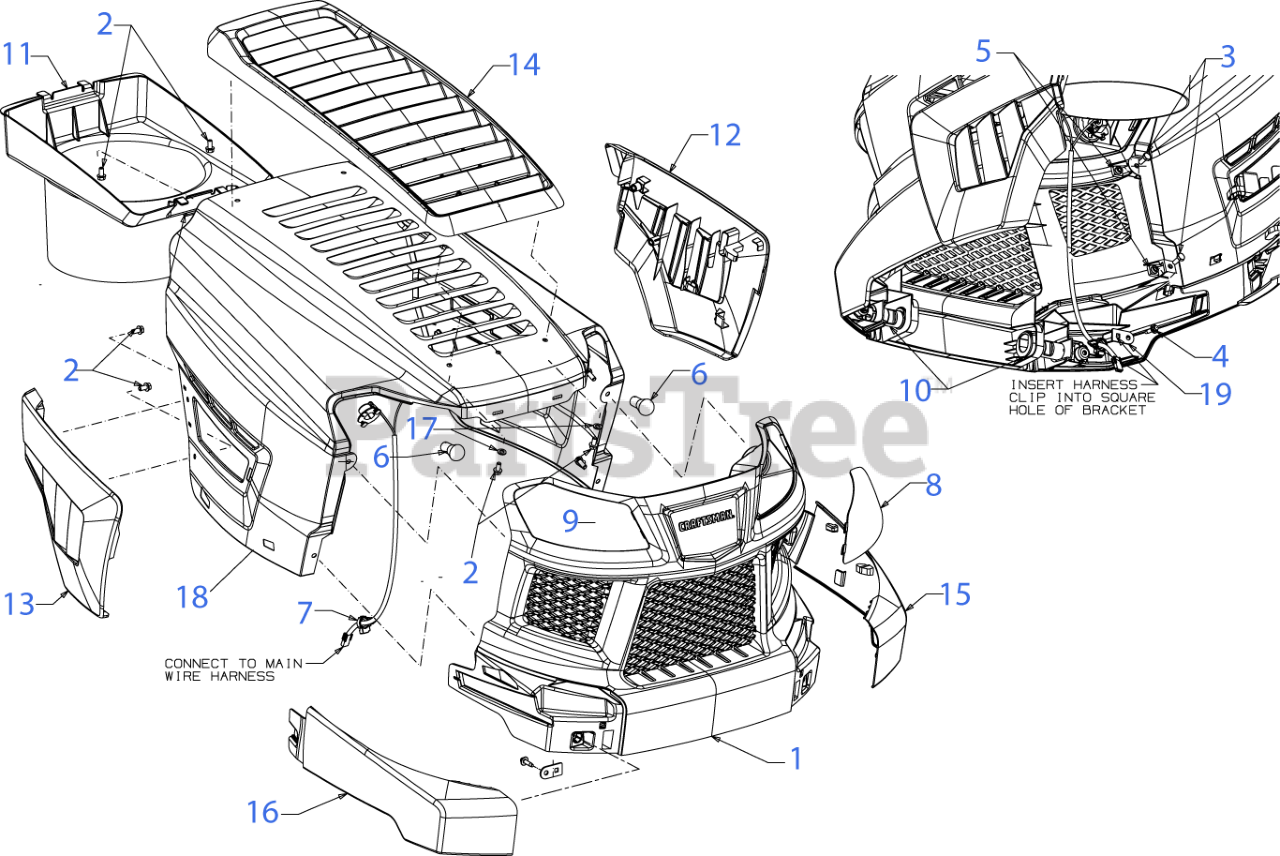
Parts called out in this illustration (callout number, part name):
1	GRILLE
2	HEX SCREW 1/4-15 x .50
3	SCREW 1/4-20 x .62 SPEC GR5
4	SCREW 1/4-10 x .750
5	SQUARE NUT 1/4-20
6	MINIATURE LAMP-12V #1156
7	HEADLIGHT HARNESS
8	GRILLE LENS (LH)
9	GRILLE LENS (RH)
10	HOOD PIVOT PIN
11	HOOD PLENUM
12	HOOD SIDE COVER (LH)
13	HOOD SIDE COVER (RH)
14	HOOD SCOOP
14	SCREW 1/4-10 x .750
15	GRILLE PANEL (LH) (LIBERTY RED)
16	GRILLE PANEL (RH) (LIBERTY RED)
17	FLAT WASHER .281 x .50 x .063
19	HARNESS CLIP BRACKET
